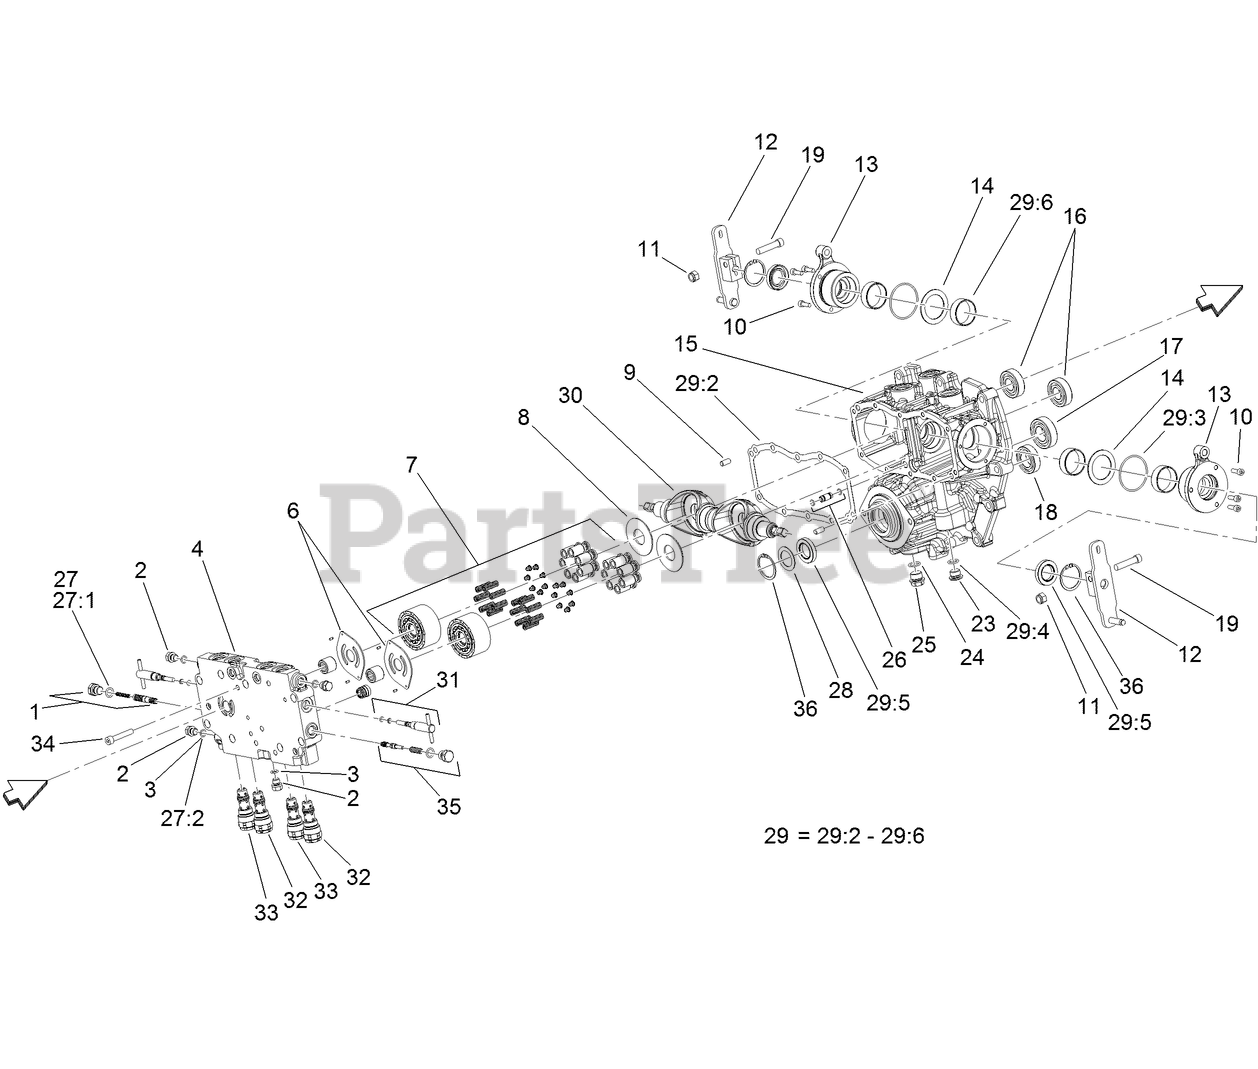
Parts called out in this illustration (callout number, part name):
1	VALVE-FLUSHING, RH
3	O RING-PLUG
4	CENTER CASE, COMPLETE
6	PLATE-VALVE
7	CYLINDER BLOCK ASM
8	PLATE-THRUST
9	PIN-PARALLEL
12	ARM-CONTROL
13	SIDE COVER ASM
14	WASHER
15	PUMP HOUSING ASM
16	BEARING
17	BEARING
18	BEARING
23	PLUG-NPTF
24	O-RING
27	CENTER CASE SEAL KIT
27:1	O-RING
27:2	O RING-PLUG
28	SPACER
29	PUMP HOUSING SEAL KIT
29:2	GASKET-CASE, CENTER
29:3	O RING-PLUG
29:6	RING-SEAL
30	PLATE-SWASH
31	VALVE-BYPASS
32	VALVE-REAR
33	VALVE-FRONT
35	VALVE-FLUSHING, LH
36	RING-SNAP
